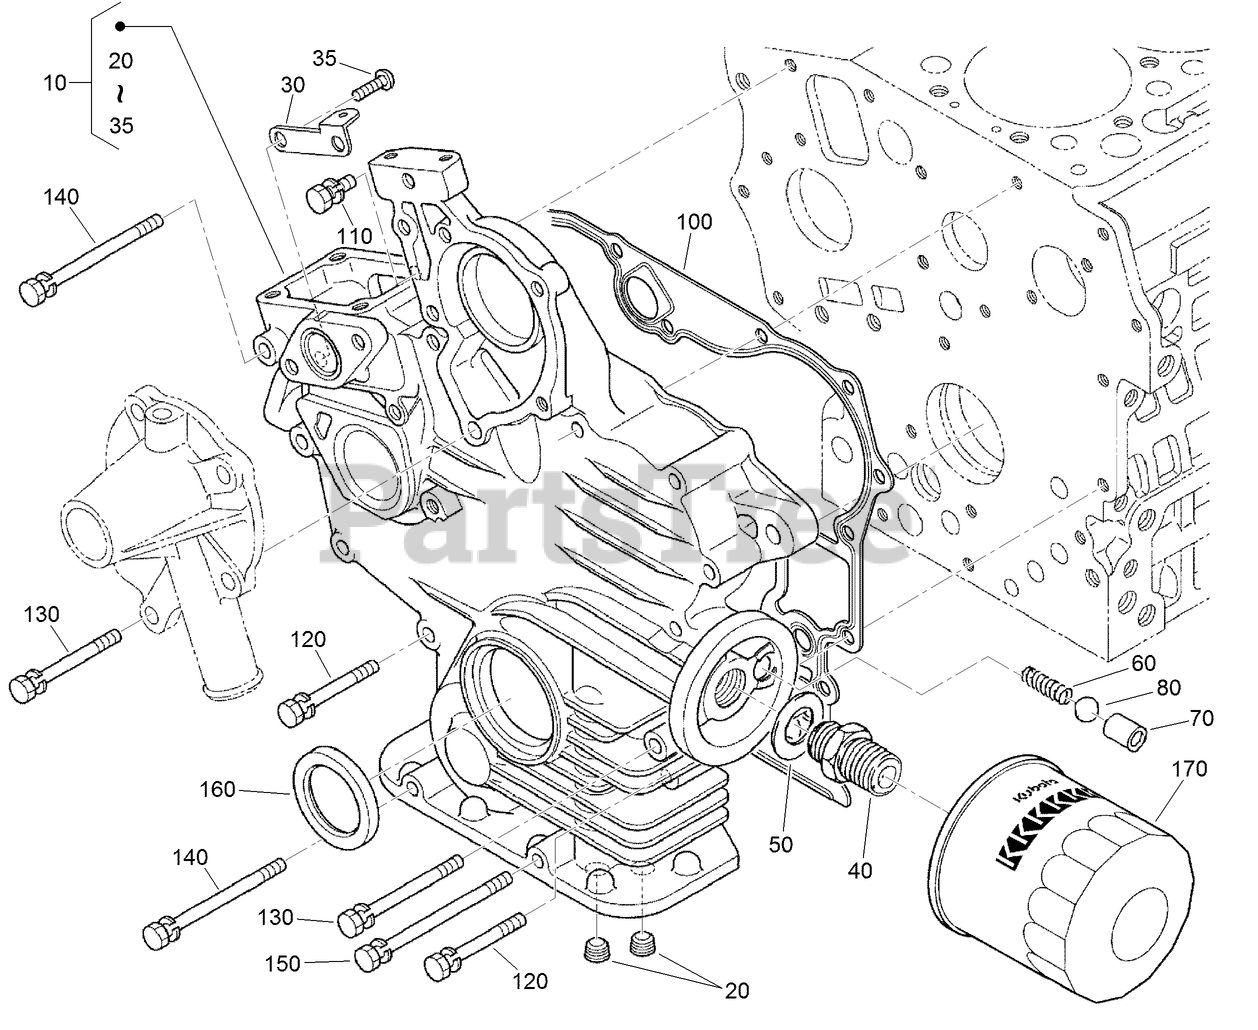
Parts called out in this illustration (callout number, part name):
30	STAY-SPRING, START
40	JOINT-PIPE
50	WASHER-PLAIN
60	SPRING
70	SEAT-VALVE
100	GASKET-CASE, GEAR
110	BOLT-FLANGE
120	BOLT-SEMS
160	SEAL-OIL
170	FILTER-OIL, ENGINE
